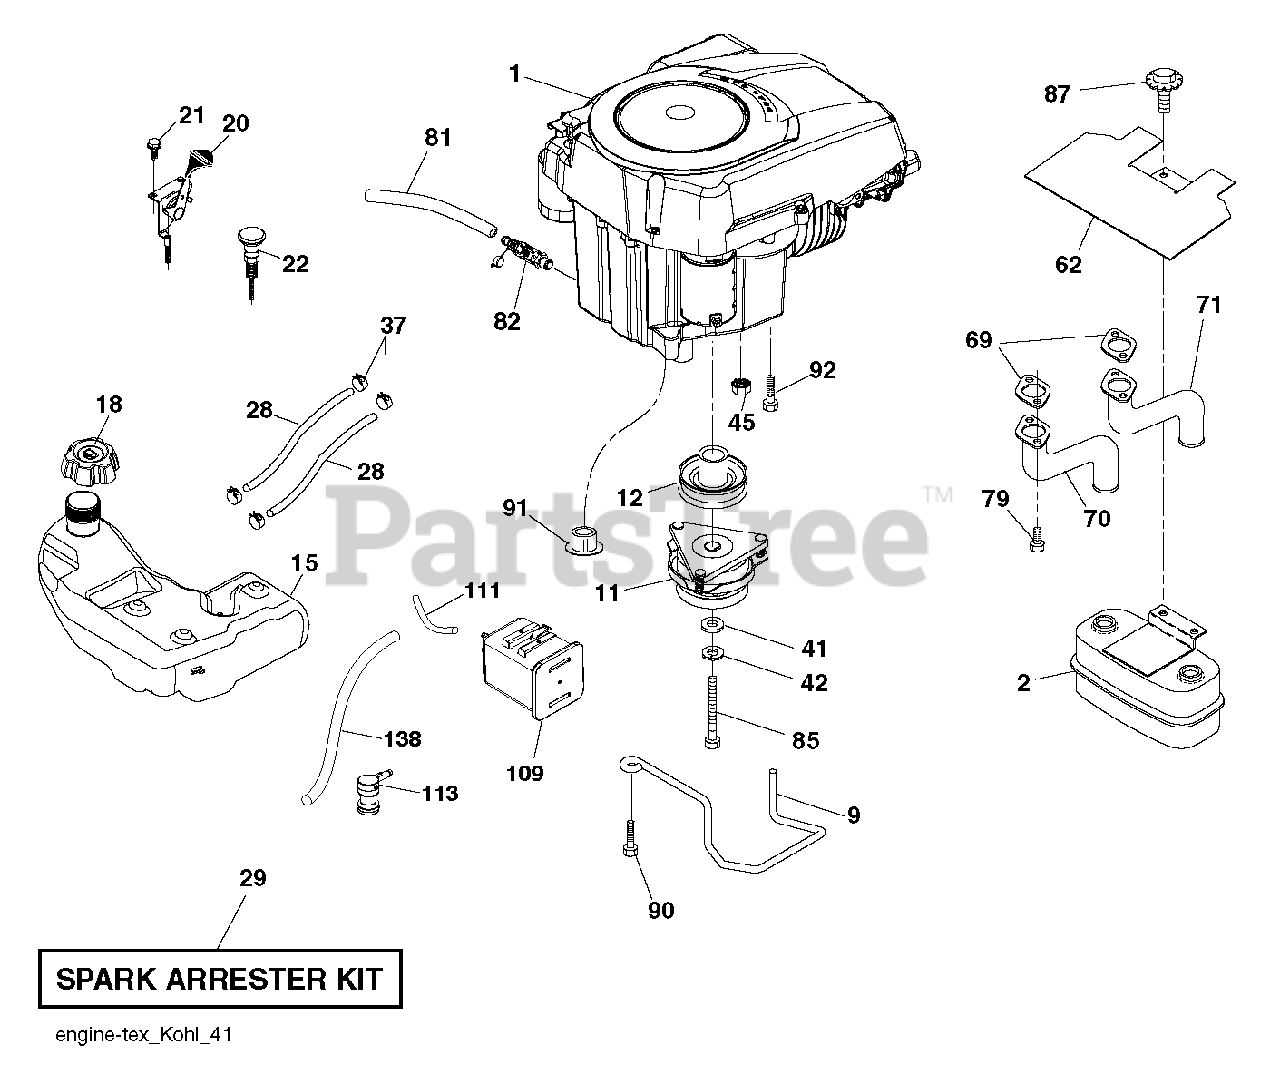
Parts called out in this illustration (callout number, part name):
2	MUFFLER.ASM.TWN.EXTNDED.DFLCTR
9	KEEPER.BELT.ENGINE.4.2
11	CLUTCH.ELECTRIC.LT.48"*
12	PULLEY.ENGINE.TUFFTORQ
15	TANK.ASM.FUEL.3GA.CARB
18	CAP.ASM.FL.RITCH.3"E10.SYM.498
20	THROTTLE CONTROL
21	SCREW.#10 X 0.750.BOS
22	CONTROL.CHOKE.ERGO.PUSH-IN.BLA
28	LINE.FUEL.64"REAR.EMIS
29	KIT.SPARK ARRESTOR 794945 B&S
37	HOSE CLAMP
42	LOCKWASHER
45	NUT
62	SHIELD.HEAT.MUFFLER
69	GASKET.EXHAUST.KOHL.CV18-CV26
70	RP.PIPE-EXHAUST LH
71	RP.PIPE-EXHAUST RH
79	SCREW.SOCKET HD.5/16-1
81	TUBE, DRAIN OIL ASM.
82	VALUE.OIL.DRAIN
85	BOLT HEX 7/16-20X4-1/4"
87	BOLT, 5/16-18 X 1 3/4
90	SCREW 3/8-16X1
91	BUSHING.1.375OD
92	SCREW 3/8-16X1
109	CANNISTER, CARBON
111	PURGE.LINE.36"REAR.CALIFORNIA
113	VALVE.SLANT.CARTRDG.90 DEG.TEX
138	RP PURGE LINE
